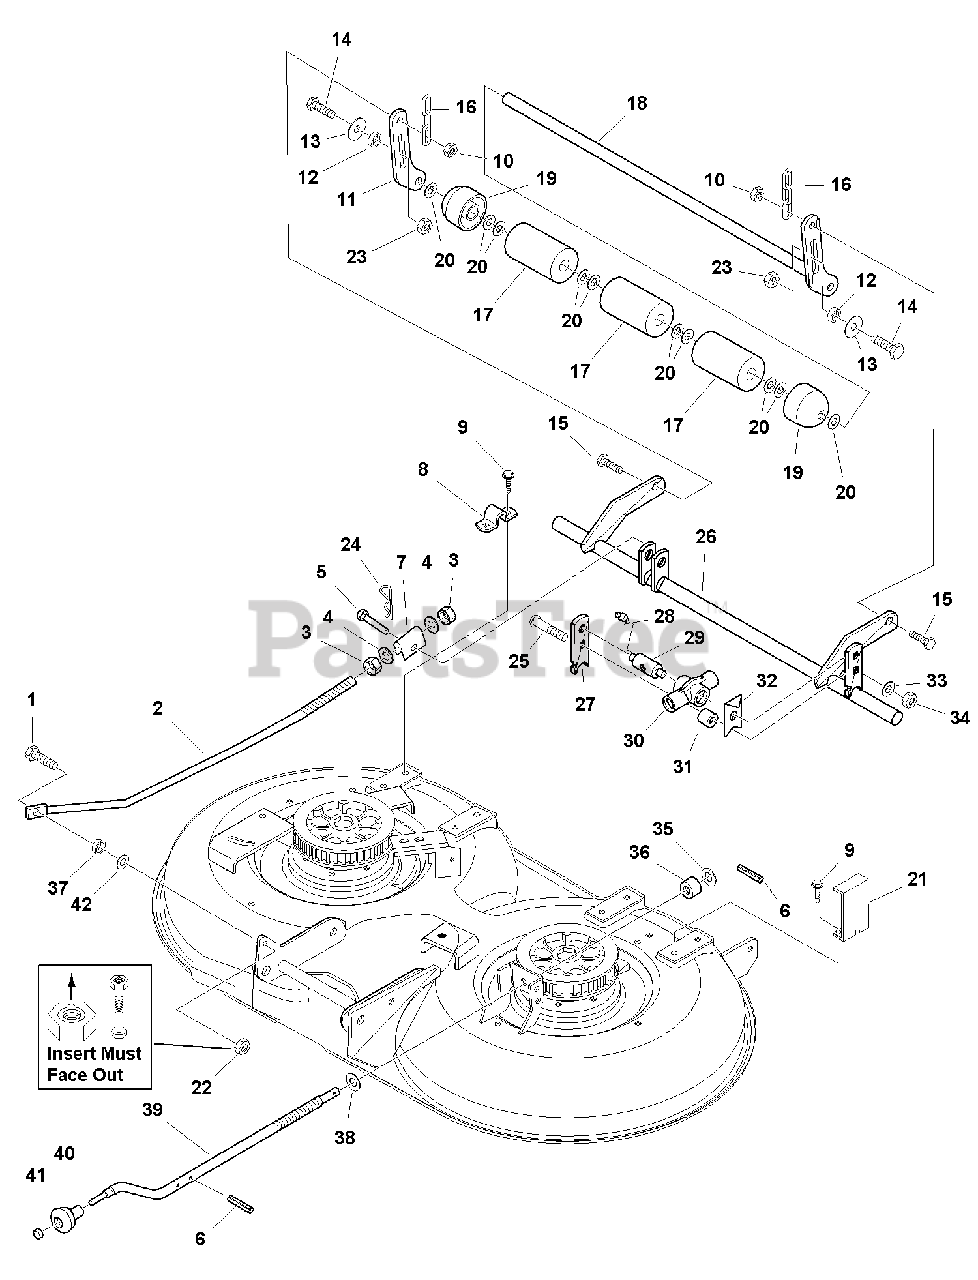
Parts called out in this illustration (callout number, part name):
1	CAPSCREW, Hex Head, 3/8-16 x 2, GR 8, Black
2	ROD & STRAP ASSEMBLY
3	NUT, Hex, 5/8-11, Black
4	WASHER, 5/8
5	PIN, Round Head, Drilled, 3/8 x 2, Black
6	PIN, Spring
7	TRUNNION
8	STRAP
9	CAPSCREW, Hex Washer Head, Tap Tite, 5/16-18 x 3/4, Black
10	NUT, Hex Flange Lock, 3/8-16, Black
11	BAR, Roller
13	WASHER, 5/16, Black
14	CAPSCREW, Hex Head, 3/8-16 x 1-1/2, Black
15	CAPSCREW, Hex Head, 5/16-18 x 1-1/4, Black
16	CHAIN, Link, 3 Links
17	ROLLER, 5/8 ID x 2-1/2 OD x 4 Long
18	SHAFT & BAR ASSEMBLY
19	ROLLER, 5/8 ID x 2-1/2 OD x 2 Long
20	WASHER, 5/8
21	PLATE, Indicator
22	NUT, Hex Lock, Aluminum Insert, 3/8-16
23	NUT, Hex Lock, 3/8-16
24	PIN, Hair
25	CARRIAGE BOLT, 1/2-13 x 2-1/2, Black
26	SHAFT ASSEMBLY, Rocker
28	FITTING, Lube
32	POINTER, Height of Cut
33	LOCKWASHER, 1/2, Black
34	NUT, Hex, 1/2-13, Black
35	WASHER, Special, Nylon
36	BEARING, Thrust
38	WASHER, 5/8, Black
39	CRANK, Height of Cut
40	KNOB, Spinner
41	NUT, Push, 3/8
42	WASHER, 3/8, Black
